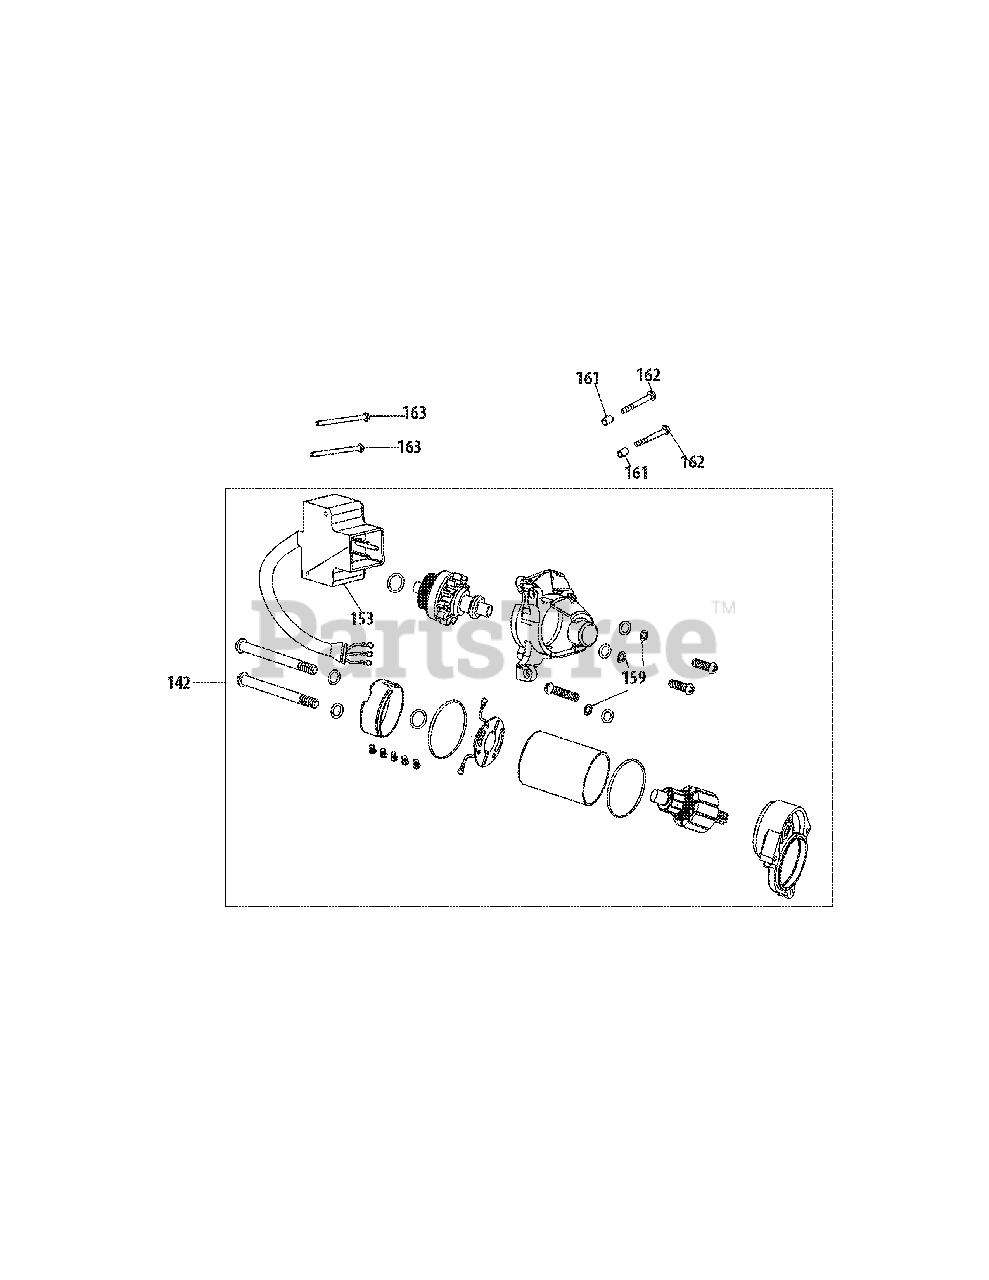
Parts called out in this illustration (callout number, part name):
142	Electric Starter
153	Cable Assembly
159	Washer, 5
161	Pin, 8×8
162	Bolt, M6×32
163	Screw, M4×55
